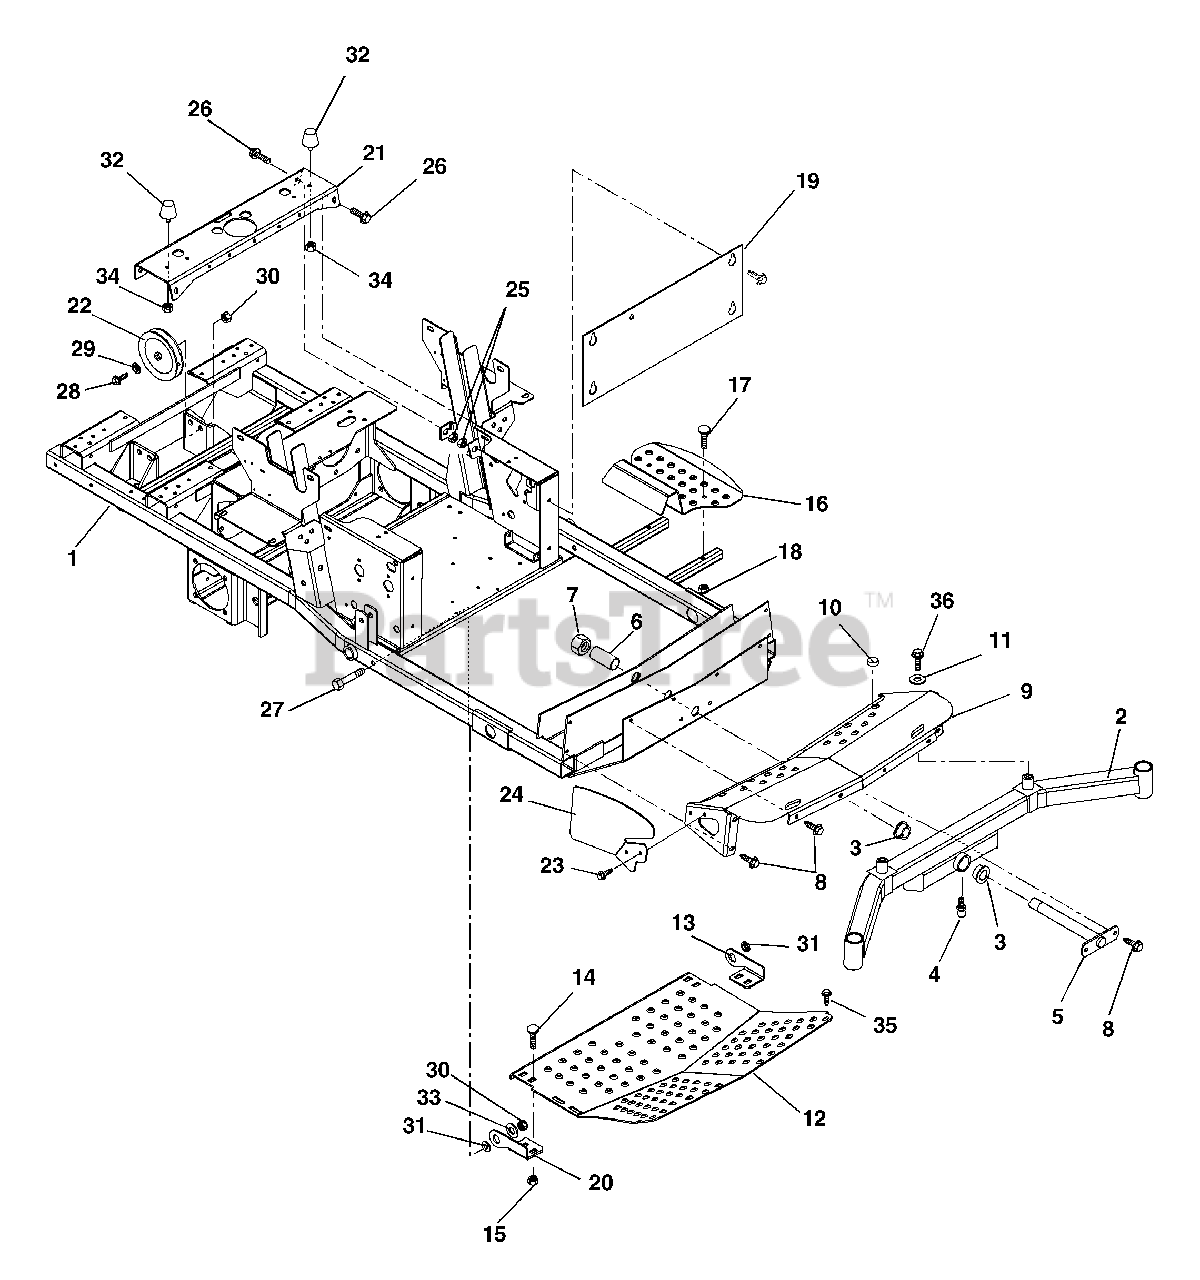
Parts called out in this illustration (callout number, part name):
1	WMT, LIQUID COOLED FRAME - BLK
2	WMT, FRONT AXLE
3	BSHG-FLG1.020X1.385X.75X1.75NY
4	FTG-LUBE .25-28X.256 YWZC
5	PIN - AXLE
6	SPACER 1.009 X 1.250 X 4.23
7	NUT-LK-NYL 1.0-14 YWZC
8	@SCR-TAP .38-16X.75 HWH TR YWZ
9	WMT, AXLE COVER
10	BUTTON BUMPER
11	BLT-HEX .50-20X1.00 GR5 YWZC
12	PANEL - INSPECTION (RED)
13	HINGE, FOOTBOARD LH
14	@BLT-RDHDSQNK .38-16X1.00 G5YZ
15	@NUT-LK-TOP-FLG .38-16 YWZC
16	STEP, INGRESS (BLACK)
17	@BLT-RDHDSQNK .31-18X1.75 G5YZ
18	@NUT-LK-TOP-FLG .31-18 YWZC
19	PLATE - KICK (RED)
20	HINGE, FOOTBOARD RH
21	CHANNEL, CROSS (BLACK)
22	PLY-V 6.0 X .500 ID DBL BRG.
23	@SCR-TAP .25-20X.50 HWH TR YWZ
24	GUARD, FOOT
25	NUT-RTNR .375-16X.37
26	BLT-SERHFWH .375-16X1.0 YWZC
27	@BLT-HEX .50-13X3.25 GR5 YWZC
28	@BLT-HEX .50-13X2.25 GR5 YWZC
29	WSHR-FL-STL .505X.880X.072 YWZ
30	@NUT-LK-TOP-FLG .50-13 YWZC
31	BSHG-FLG .515X.750X.285X1.120
32	BUMPER, RUBBER CONE,STUD MOUNT
33	@WSHR-FL-STL.563X1.38X.109YWZC
34	@NUT-SPNLK-FLG .312-24 YWZC
35	@SCR-TAP .38-16X1.00 HWH TR YZ
36	WSHR-FL-STL .518X2.0X.105 YWZC
